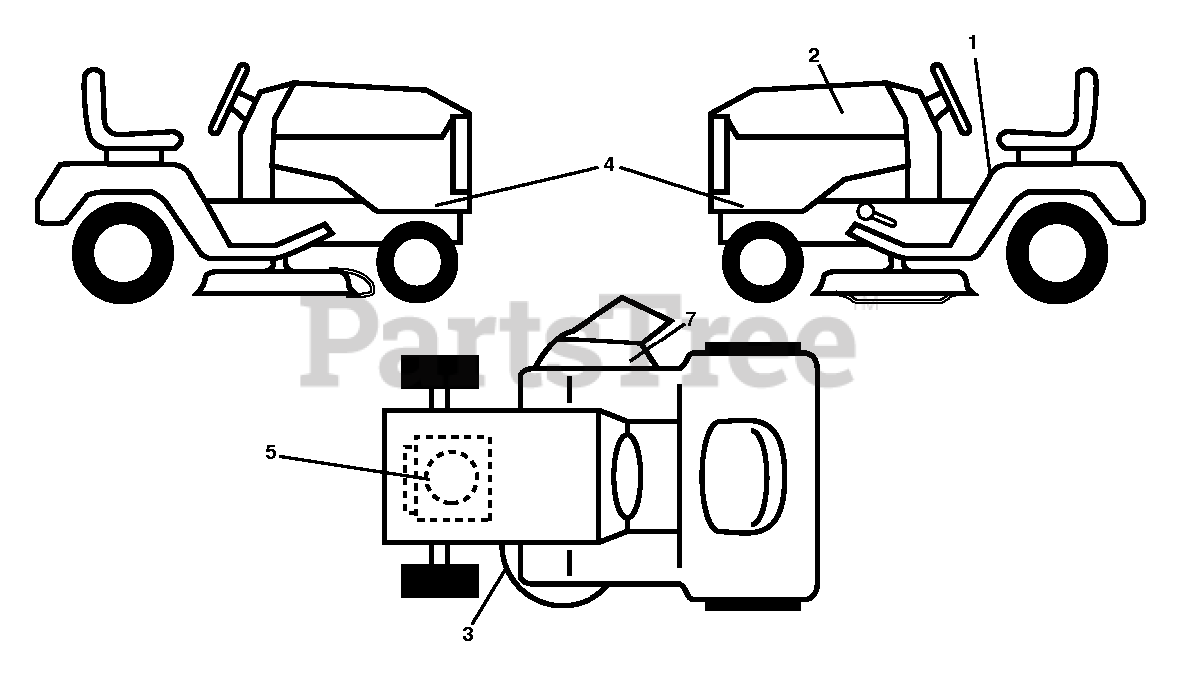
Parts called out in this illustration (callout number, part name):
1	DECAL.WARNING.2007.ENG/FR
3	DECAL.V-BELT.SCH.42/46"MEC/ELE
5	DECAL.BS.ENDUR.18_5HP.382024
7	DECAL, DECK DEFLECTOR, WARNING
